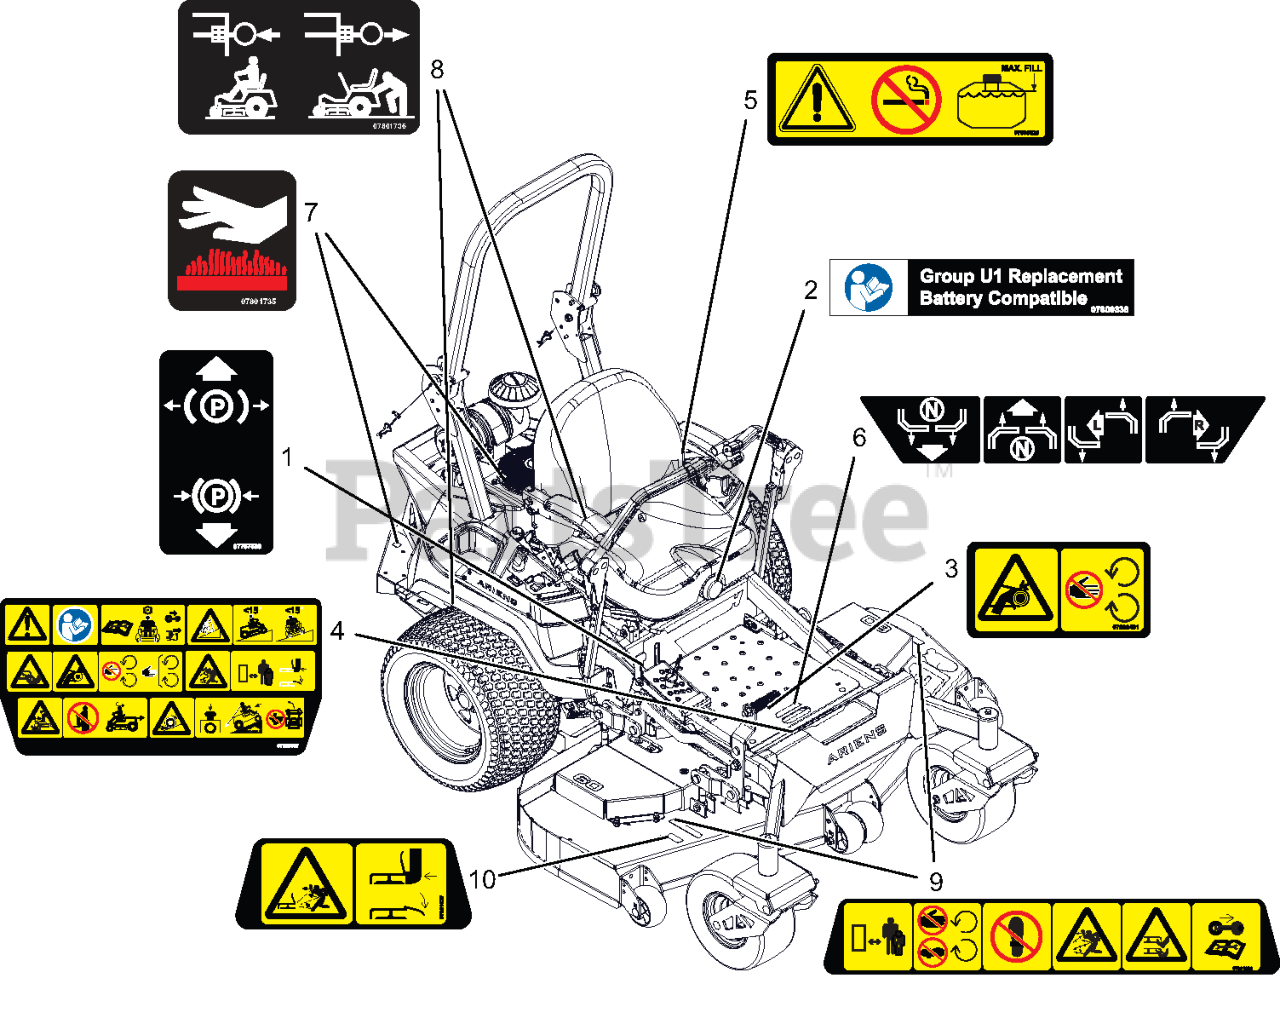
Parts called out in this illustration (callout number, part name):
1	DECAL, PARKING BRAKE LEVER
2	DECAL, U1 BATTERY REPLACEMENT
3	DECAL, SAFETY - GUARDING
4	DECAL, MAIN SAFETY
5	DECAL, FUEL WARNING
6	DECAL, INSTRUCTION - STEERING
7	DECAL- HOT SURFACE
8	DECAL- TRANSAXLE DISCONNECT
9	DECAL- SAFETY - MOWER DECK
10	DECAL- SAFETY - DECK GUARDING
